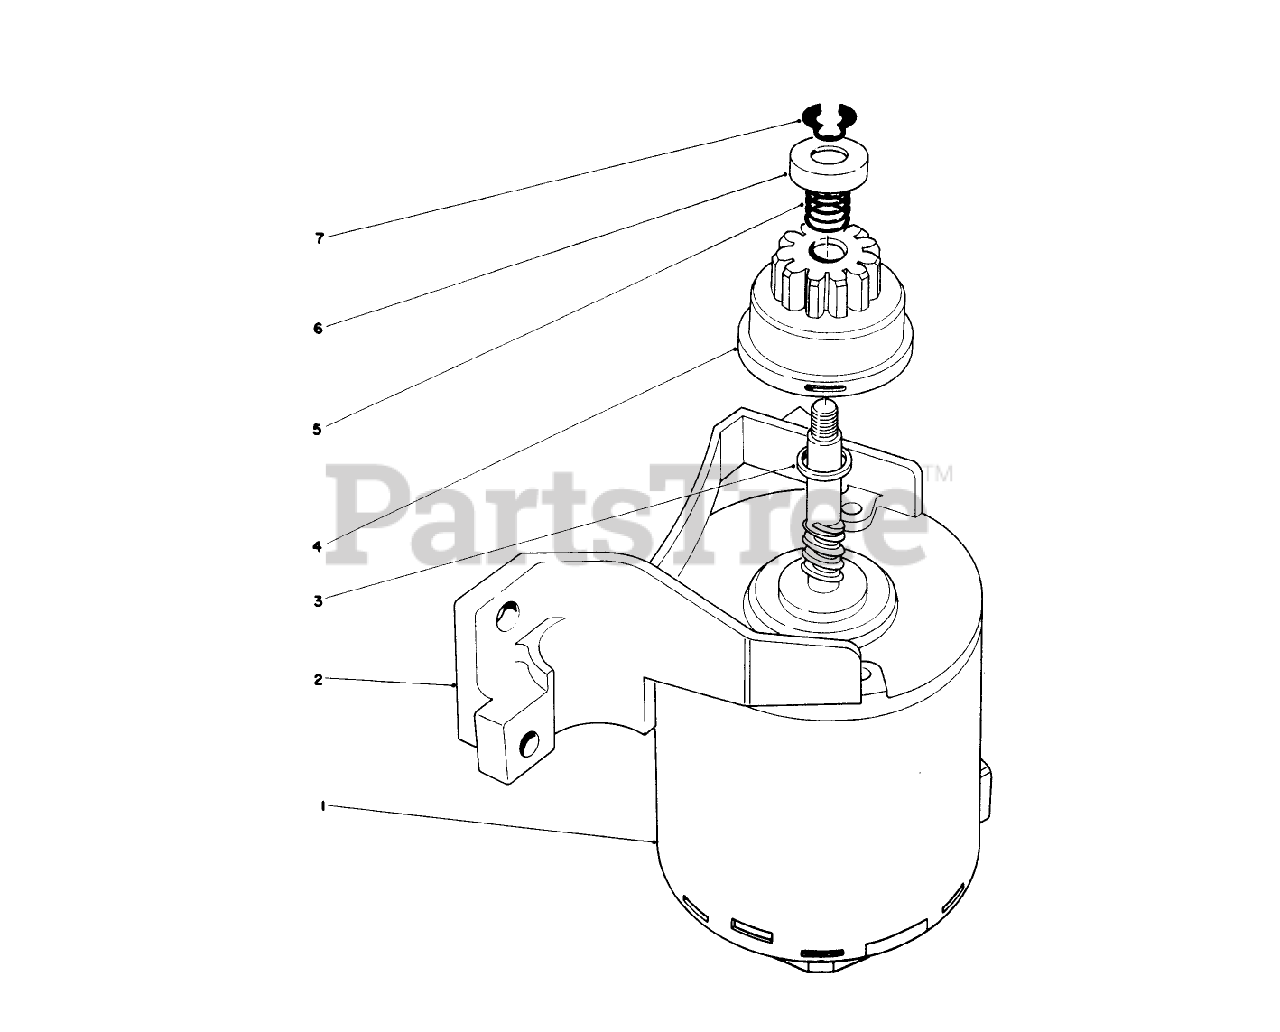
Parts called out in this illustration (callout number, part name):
1	END FRAME W/BRUSH
2	BRKT END FRAME
3	SPACER
4	PINION ASM
5	COMPRESSION SPRING
6	PINION STOP
7	RING-RETAINING
